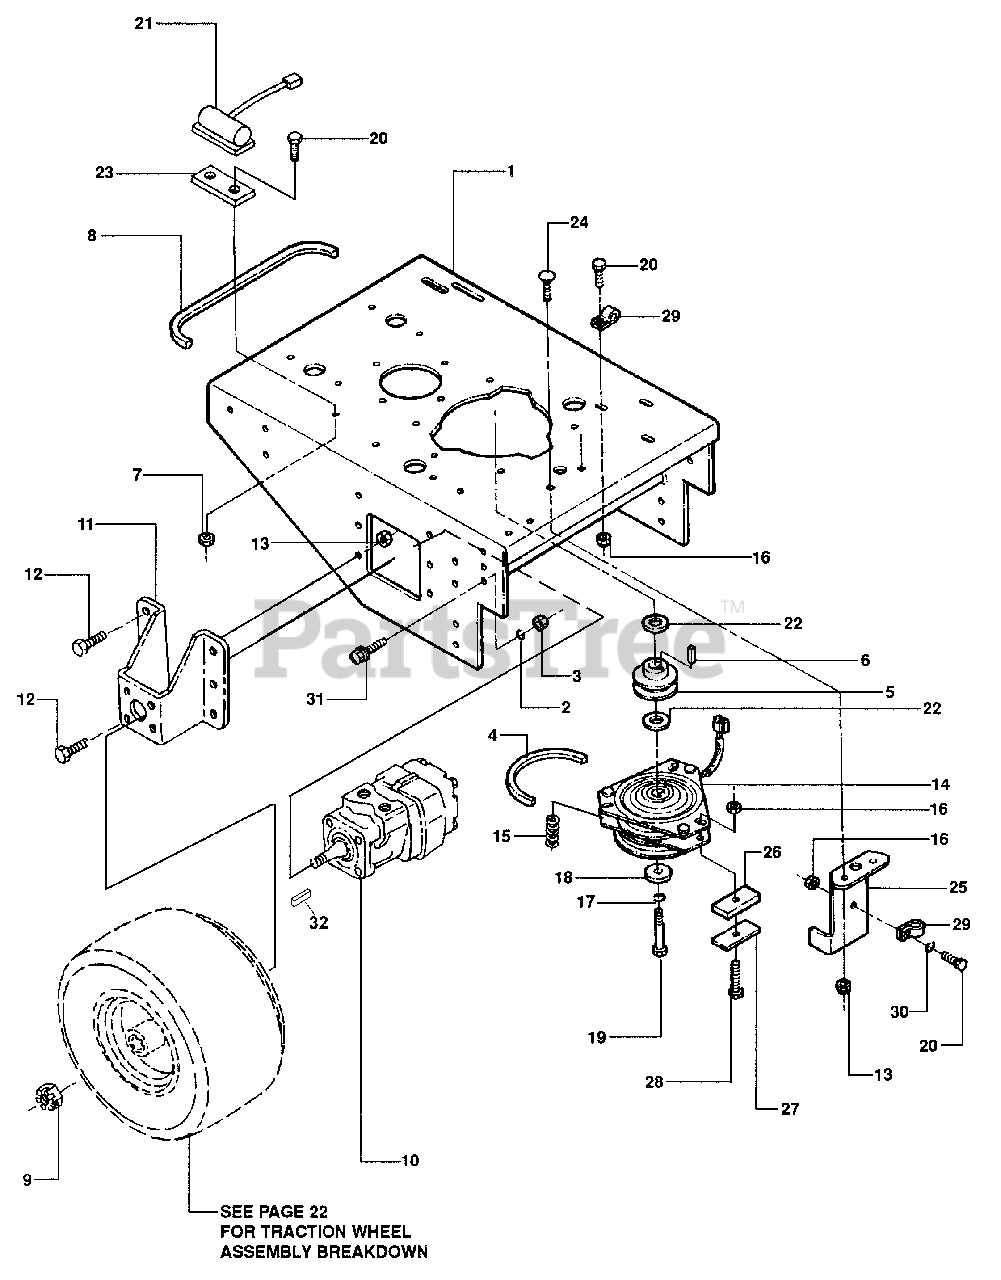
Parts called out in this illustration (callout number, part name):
1	WELDMENT, Rear Deck
2	WASHER, 1/2" Split Lock
3	NUT, 1/2-13 Hex
4	BELT, Engine/Deck,
5	PULLEY, Engine/Hydro 4"
6	KEY, 1/4" Square Tapered
7	NUT 5/16-18 Nyloc
8	BELT, Engine/Hydro
9	NUT, Wheel Locking
10	WHEEL MOTOR
11	WHEEL MOUNT
12	SCREW, 3/8-16 X 1" Hex Head
13	NUT, 3/8-16 Nyloc
14	CLUTCH, Electric
15	SPRING, Coil
16	NUT, 3/8-24 Hex Lock
17	WASHER, 7/16" Lock
18	SPACER
19	SCREW, M10-1.5 X 55mm Hex Head Cap
20	SCREW, 5/16-18 X 3/4"
21	CAPACITOR
22	BUSHING, 1.5" O.D. X 1" I.D.
23	MOUNT, Capacitor
24	BOLT, 3/8-16 X 1-1/4" Carriage
25	BRACKET, Clutch
26	BUMPER, Electric Clutch
27	SUPPORT, Electric Clutch Bumper
28	BOLT, 5/16-18 X 1"
29	"J" CLIP, Clutch
30	WASHER, 5/16 Split Lock
31	BOLT, 1/2-13 X 1-1/4" Hex Flange Lock
32	Key, 3/16" Square x 3/4" Long
